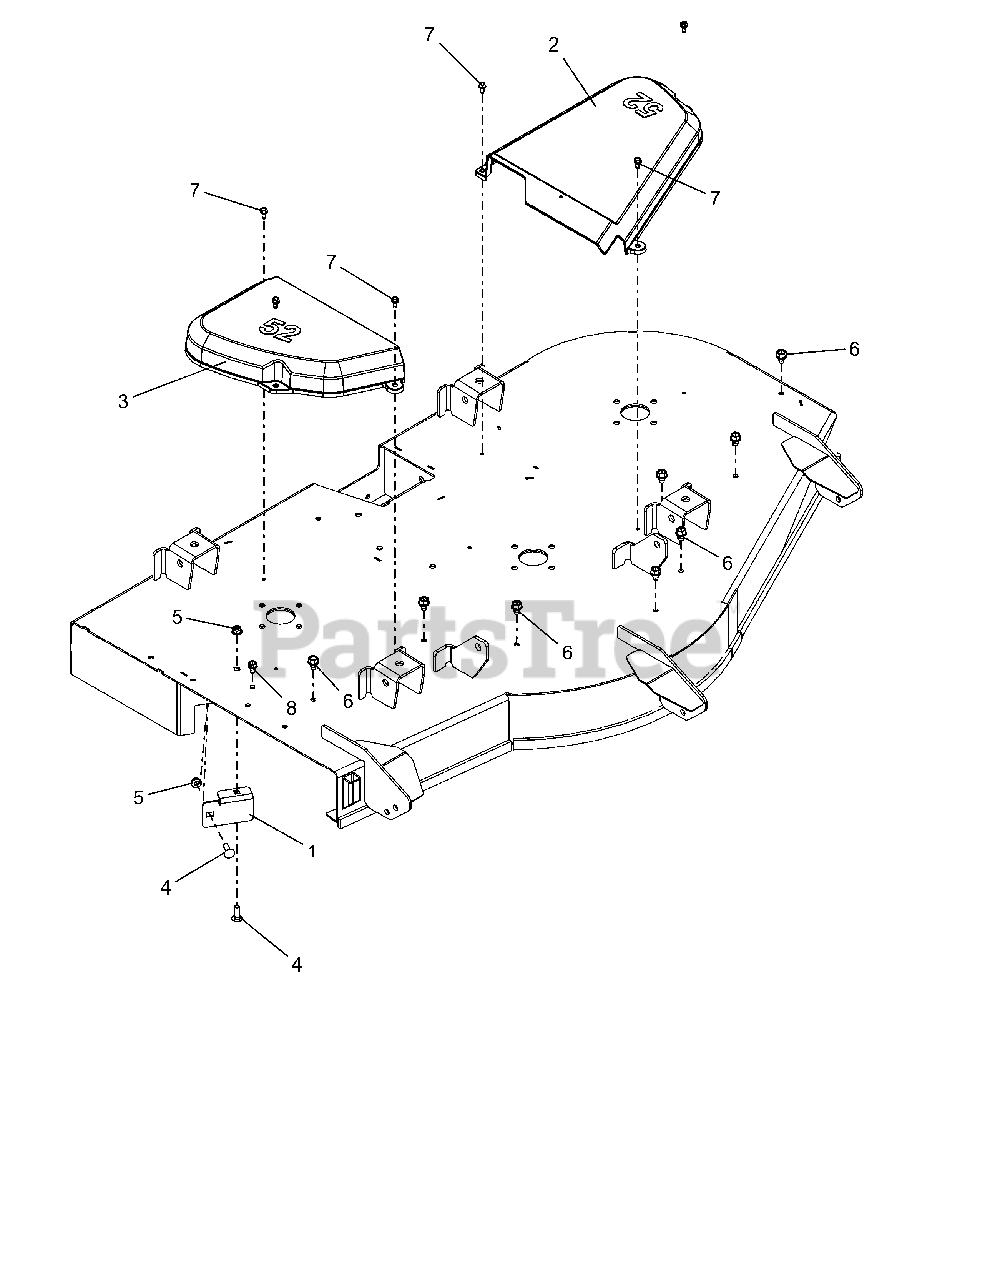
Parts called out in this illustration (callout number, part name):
1	STRIP, DEFLECTOR - 52"
2	COVER, BELT 52" LH
3	COVER, BELT 52" RIGHT
4	BLT,RHSN .31-18X1.00 G5 ZCC
5	NUT,NYL-FLG .31-18 GF ZCC
6	SCR,TAP .375-16X.50 HWH TR ZCC
7	SCR-TAP .25-20X.50 HWH ZCC
8	@SCR-TAP .31-18X.50 HWH TR YWZ
